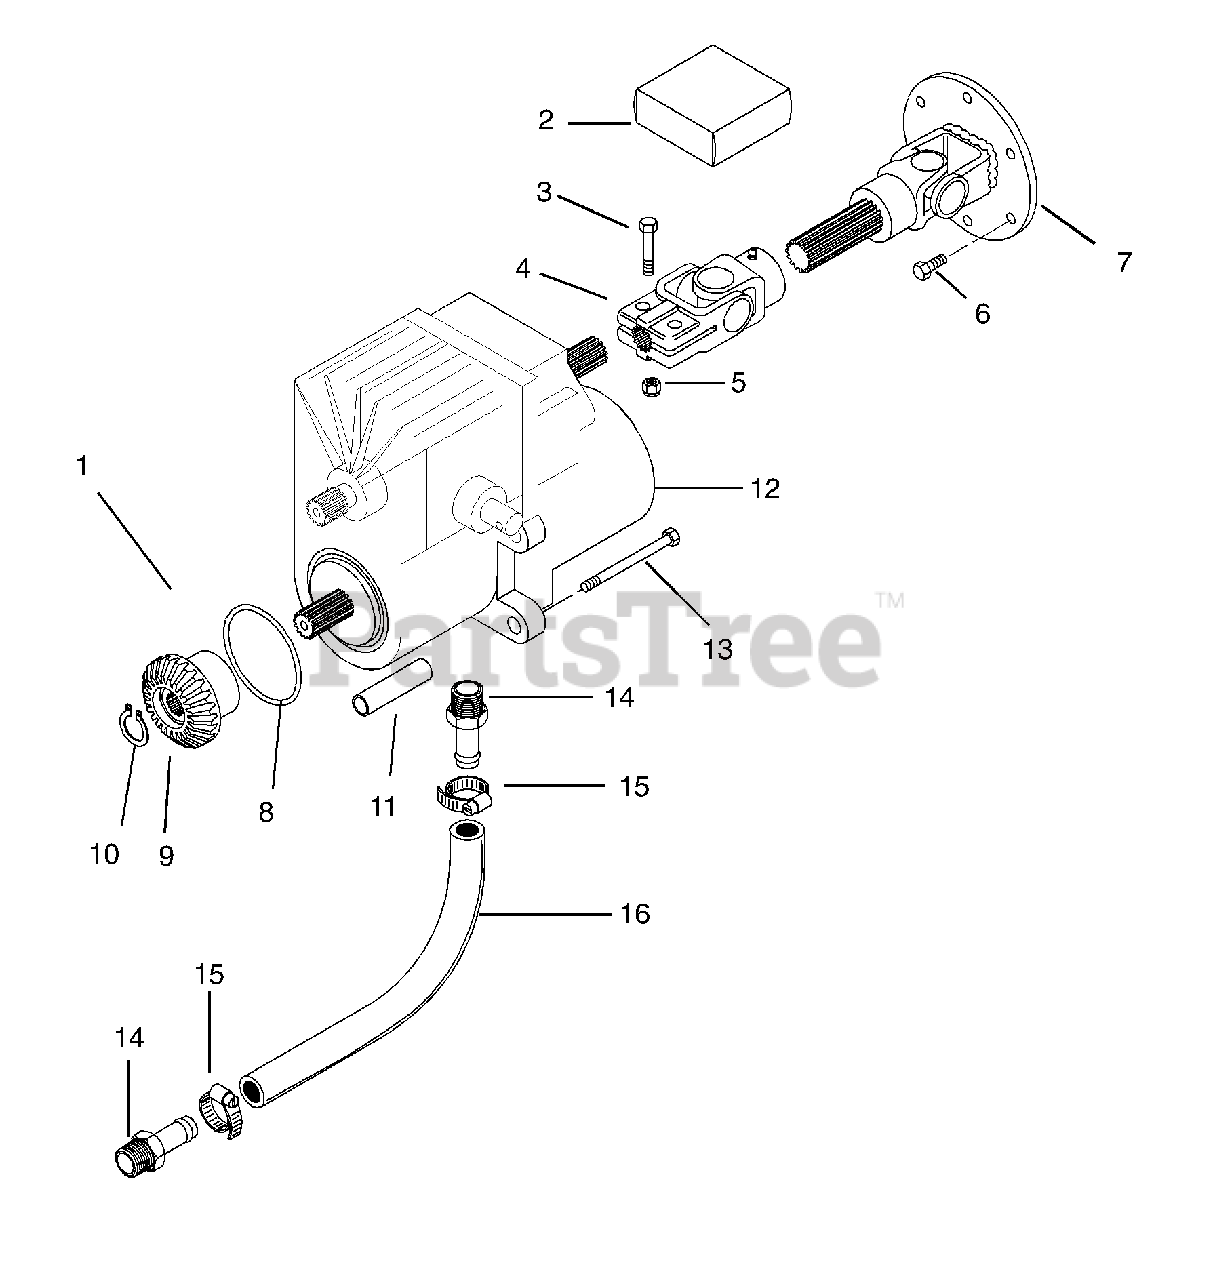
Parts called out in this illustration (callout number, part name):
1	Transmission, Hydraulic
2	Kit, U-Joint Repair
3	Bolt-Hex .38-16 x 1.75 Grade 5
4	Assembly, U-Joint
5	Nut-Locking-Center .38-16
6	Bolt-Hex M10 x 1.25 x 20
7	Adapter, Flywheel
8	O-Ring 3.0 x 3.187 x .093
9	Gear
10	Ring-Retaining-External .579 x .930
11	Spacer .385 x .625 x 2.69
12	Oil Filter
13	Bolt-Hex .38-16 x 4.00 Grade 5
14	Fitting-Adapter 88-14
15	Clamp, .88 Diameter Hose
16	Ft. Hose .62 ID x .91 OD
